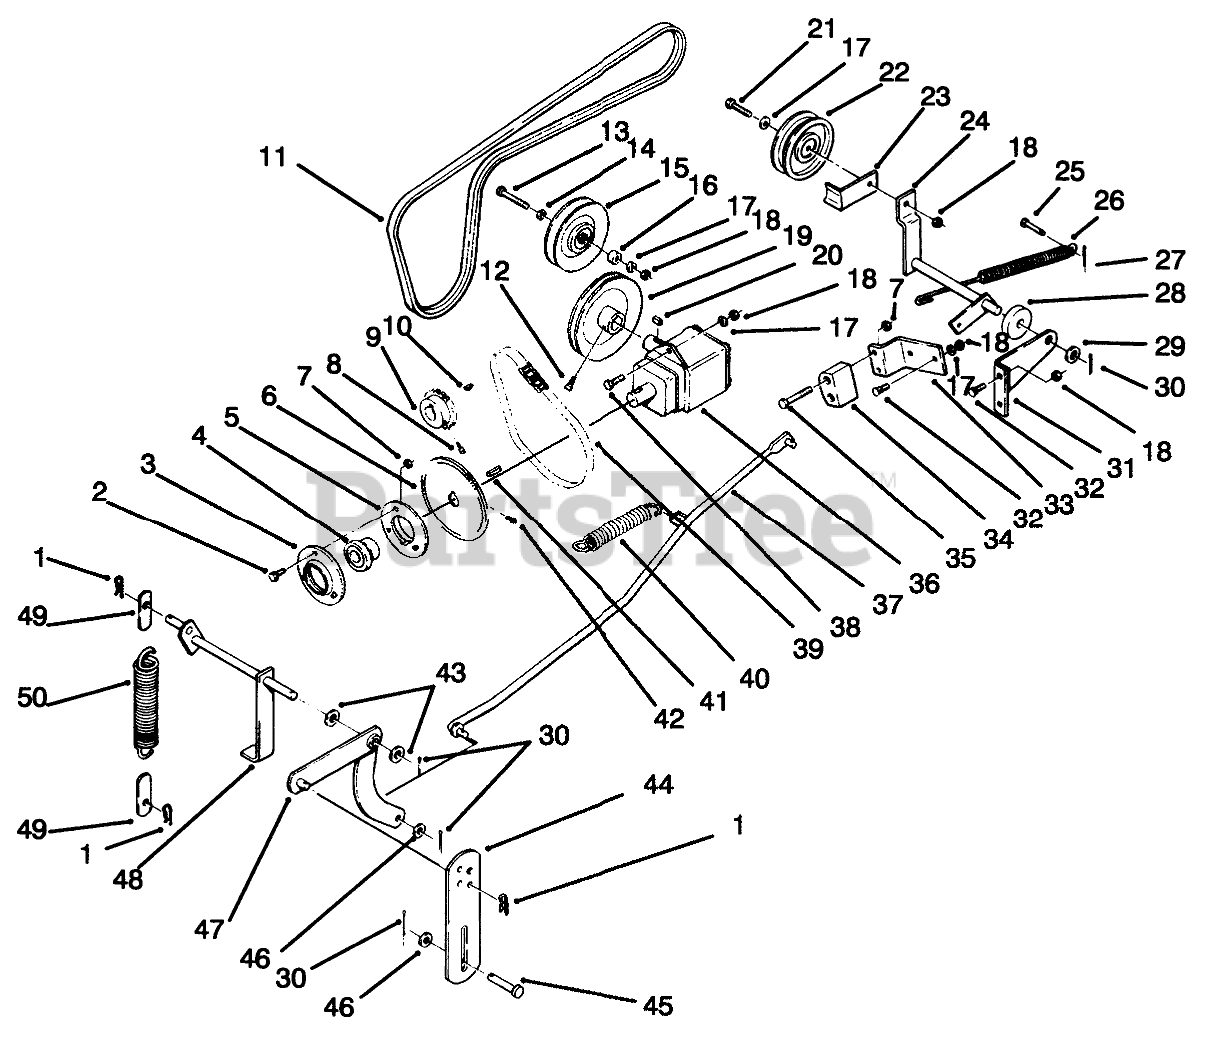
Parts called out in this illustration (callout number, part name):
1	Hairpin Cotter
2	BOLT-CARR
3	Flange
4	BEARING AND COLLAR
5	FLANGE-RELUBE
6	SPROCKET-33T
7	NUT-LOCK, NI
8	SCREW-SET
9	SPROCKET-15 T
10	KEY-HI PRO
11	V-BELT 64 .5EL
12	SCREW-SQH
13	SCREW-HH
14	WASHER
15	"V" Pulley
16	SPACER
17	WASHER-FLAT
18	NUT-LOCK, NI
19	PULLEY - GEAR BOX
20	KEY-WOODRUFF
21	SCREW-HH
22	PULLEY-FLAT IDLER
23	Spacer
24	WLDMT-IDLER ARM R
25	PIN-CLEVIS
26	SPRING
27	PIN-COTTER
28	RUBBER WASHER
29	WASHER-FLAT
30	PIN-COTTER
31	BRACKET-PIVOT R
32	BOLT-CARR
33	BRACKET-TIGHTENER R
34	Chain Tightener
35	SCREW-HH
36	GEAR-BOX L.H.
37	WLDMT-LIFT ROD R
38	BOLT-CARR
39	CHAIN
40	SPRING
41	KEY
42	SCREW-SET, SQH
43	Washer
44	LINK-LIFT R
45	CLEVIS PIN
46	WASHER-FLAT
47	WLDMT-SNOWTHWR LI R
48	WLDMT-SPRING SUPP R
49	RETAINER-SPRING R
50	SPRING
